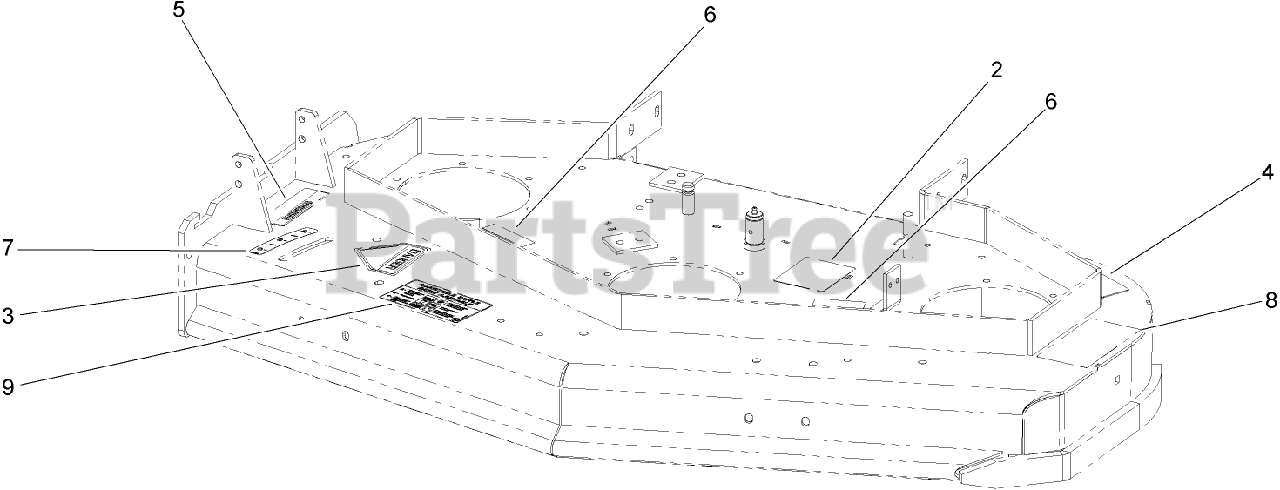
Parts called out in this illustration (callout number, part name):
2	DECAL-ROUTING, BELT
3	DECAL-DANGER
4	DECAL-TORQUE, BOLT
5	DECAL-WARNING
6	DECAL-COVER, MISSING
7	DECAL-SETTING, BAFFLE
8	DECAL-DANGER, THROWN OBJECT
9	DECAL-ADJUSTMENT, BAFFLE
